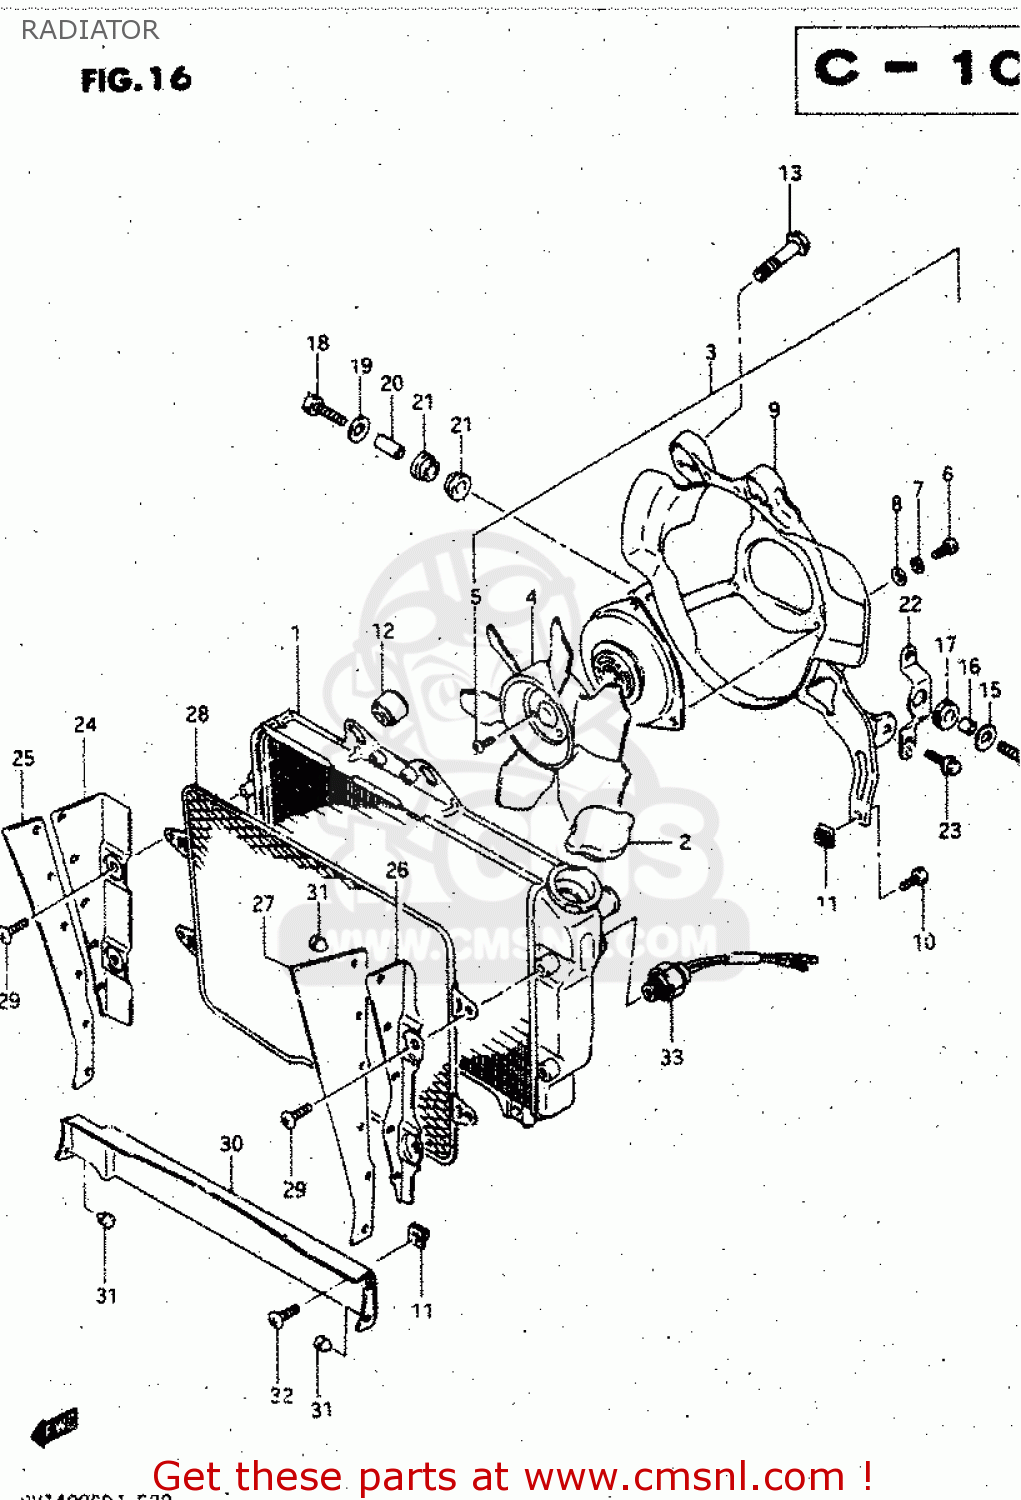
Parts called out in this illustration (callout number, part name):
1	RADIATOR,WATER
2	CAP,RADIATOR
3	FAN ASSEMBLY,RADIATOR
4	FAN
5	BOLT
6	SCREW 5X10
7	LOCK WASHER
8	WASHER
9	SHROUD
10	BOLT,RADIATOR FAN
11	NUT,RADIATOR
12	CUSHION,RADIATOR NO.1
13	BOLT
14	BOLT
15	WASHER
16	SPACER (7X9X7)
17	CUSHION
18	BOLT(6X35)
19	WASHER(6,5X22X1.6)
20	SPACER (6.4X9X20)
21	CUSHION
22	BRACKET COMP,RADIATOR
23	BOLT 6X16
24	PLATE,RADIATOR,RIGHT
25	SEAL,RADIATOR,RIGHT
26	PLATE,RADIATOR,LEFT
27	COVER,RADIATOR
28	NET, RADIATOR
29	SCREW
30	COVER,RADIATOR,LOWER
31	CUSHION
32	SCREW
33	SWITCH
